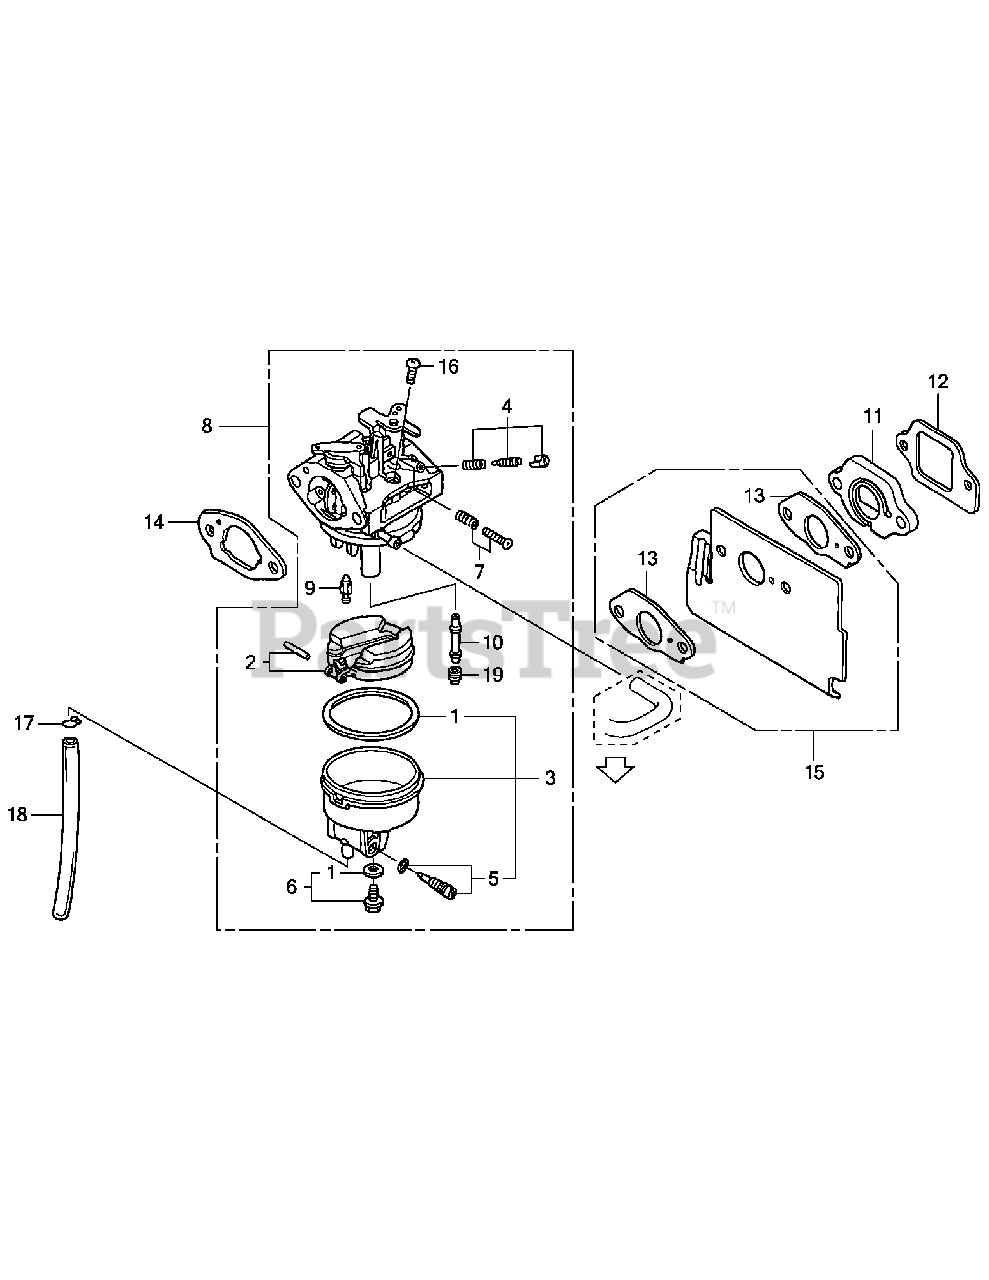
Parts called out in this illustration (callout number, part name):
1	Packing Set
3	Chamber Set, Float
5	Screw Set, Drain
6	Screw Set
7	Screw Set (Throttle Stop)
8	Caburetor Assembly (BB61J A)
9	Valve Complete, Float
10	Nozzle, Main
11	Insulator, Carburetor
12	Packing, Insulator
13	Packing, Caburetor
14	Packing, Caburetor
15	Guide Complete, Air
16	Screw, Pan 5 x 6
17	Clip, Tube (B6.5)
18	Tube, Vinyl 4 x 7 x 150
19	Jet, Main, #60
19	Jet, Main, #62
19	Jet, Main, # 65
